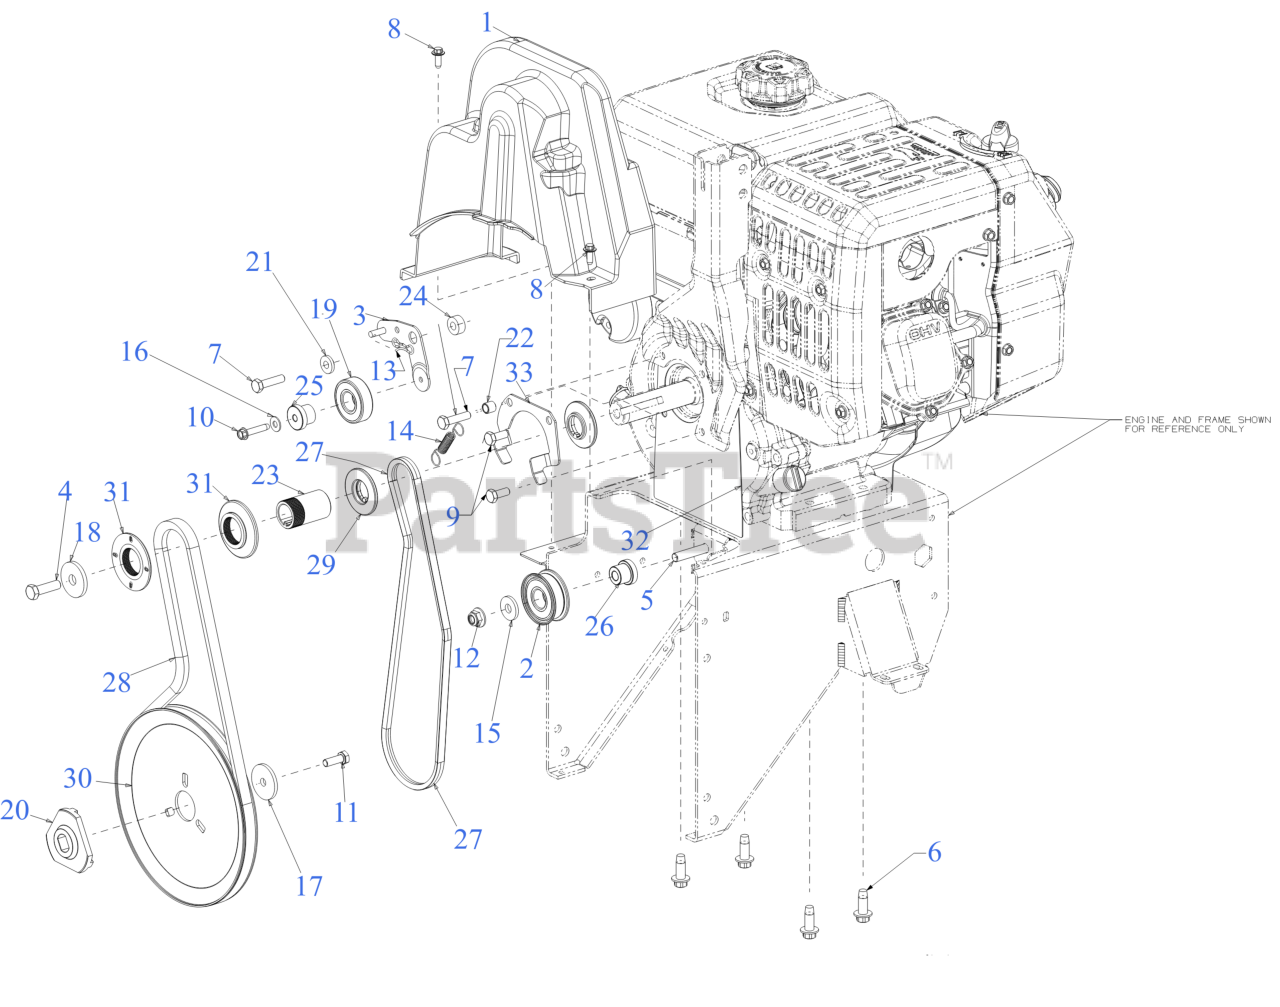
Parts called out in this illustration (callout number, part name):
1	BELT COVER ASSEMBLY
2	IDLER PULLEY ASSEMBLY
3	HYDRO DRIVE IDLER ASSEMBLY
4	SCREW 3/8-24X1.25
5	HEX SCREW 3/8-16 x 1.75 GR5
6	SCREW 3/8-16 x 1
7	SCREW 5/16-24 x 1.25 GR5
8	SCREW M6-1 x .625
9	SCREW 5/16-24 x .750 GR5
10	SCREW 1/4-20 x 1.25
11	SCREW 5/16-24 x .875 GR5
13	BOW TIE COTTER PIN 1/4-5/16
14	EXTENSION SPRING .300ID x 2.408LG
15	FLAT WASHER .385 x 1.00 x .135
16	FLAT WASHER
17	FLAT WASHER
18	FLAT WASHER .45 x 1.5 x .172 HT
19	BALL BEARING
20	ADAPTER PULLEY .75 DIA W/DD
21	SHOULDER SPACER
22	BUSHING
23	PULLEY SPACER
24	IDLER BRACKET SPACER .340X.750X.330
25	SHOULDER SPACER
26	SHOULDER SPACER .385 x .785 x .538
27	HYDRO DRIVE BELT
28	V-BELT .500 x 41.495
29	HALF PULLEY-3/8 V x 1.7160
30	AUGER PULLEY 8.5 OD
31	HALF PULLEY A2.43 x 1.140 SPLINE
32	ENGINE PLATE (FRONT COVER)
33	BELT KEEPER BRACKET
